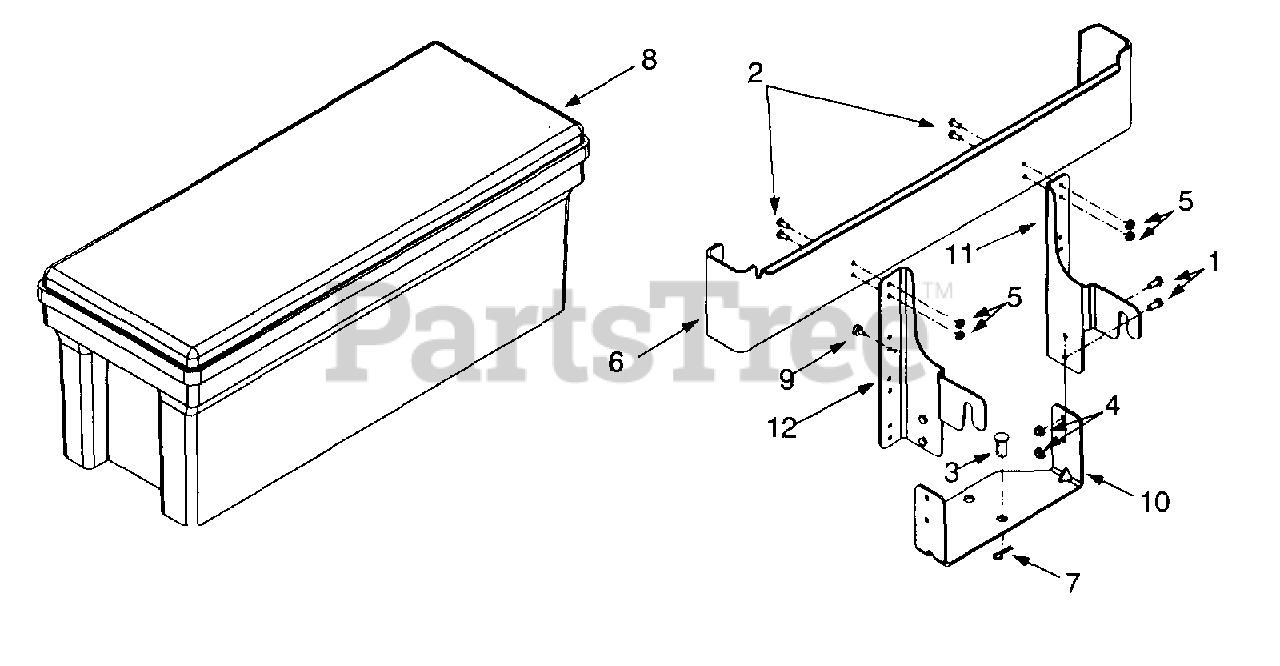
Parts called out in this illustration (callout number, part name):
1	Hex Cap Screw, 5/16-18 x .75
2	Hex Cap Screw, 1/4-20 x .62
4	Hex Flange Lock Nut, 5/16-18
5	Hex Flange Lock Nut, 1/4-20
8	Plastic Tool Box
9	Bumper, .62 Dia. x .3
